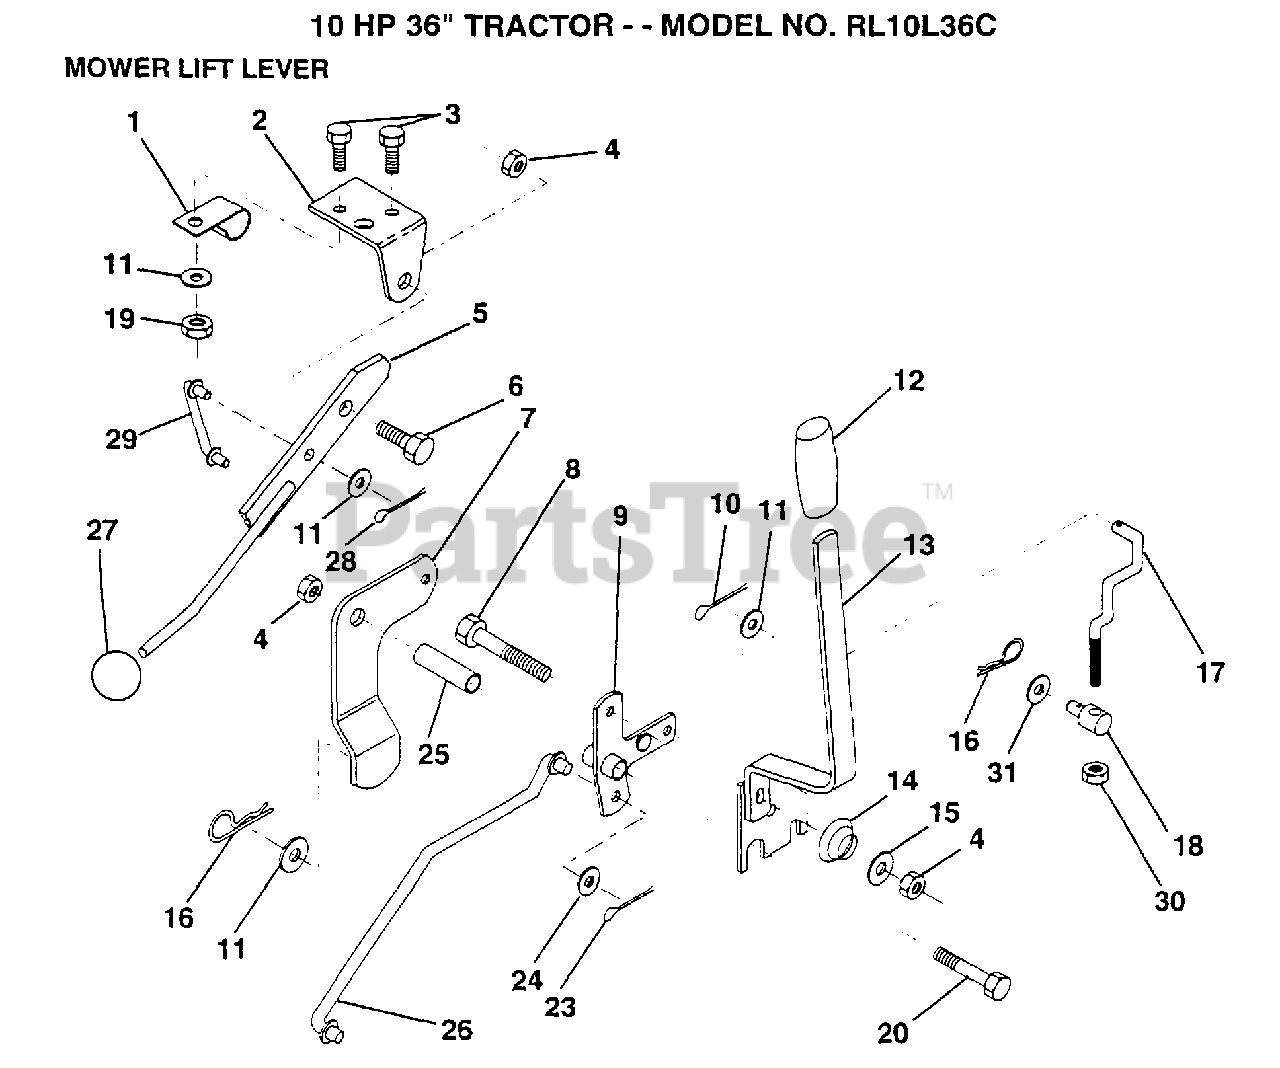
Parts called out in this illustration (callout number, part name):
1	"CLIP,INSULATOR"
2	BRKT CLUTCH
3	BOLT
4	NUT
5	CLUTCH LEVER AS
6	"BOLT, SHOULDER LT"
7	MWR CLUTCH ARM AS
8	BOLT
9	"BELLCRANK,LIFT"
10	COTTER PIN
11	WASHER
13	HANDLE.ASM.LIFT
14	SPRING COMPRESSIO
15	WASHER T
16	SPRING.RETAINER
17	"LINK,LIFT FRT"
18	TRUNION ADJ
20	BOLT
23	PIN COTTER 1/8
25	TUBE SPACER
26	ROD LIFT MOWER
27	KNOB T(3/8 HOLE)
29	CLUTCH LINK
30	NUT
31	WASHER
